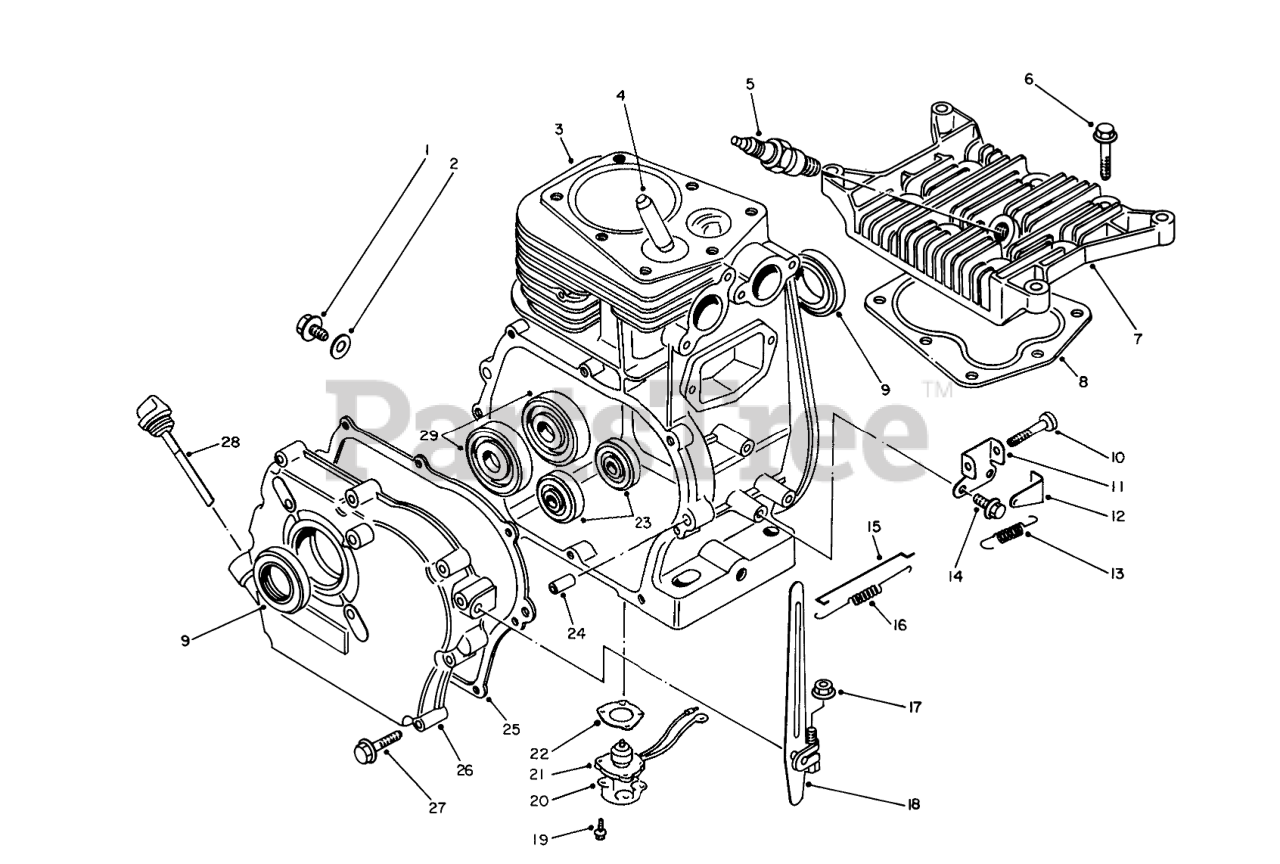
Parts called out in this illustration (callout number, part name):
1	Drain Plug
2	GASKET
3	Cylinder
4	VALVE GUIDE
5	SPARK PLUG
7	Cylinder Head
8	GASKET
9	OIL SEAL
11	Bracket
13	SPRING
15	Rod
16	SPRING
18	Control Lever
20	Plate
21	SENSOR
22	GASKET
23	Bearing
25	Gasket
26	Cover
28	Gasket
29	Screw
